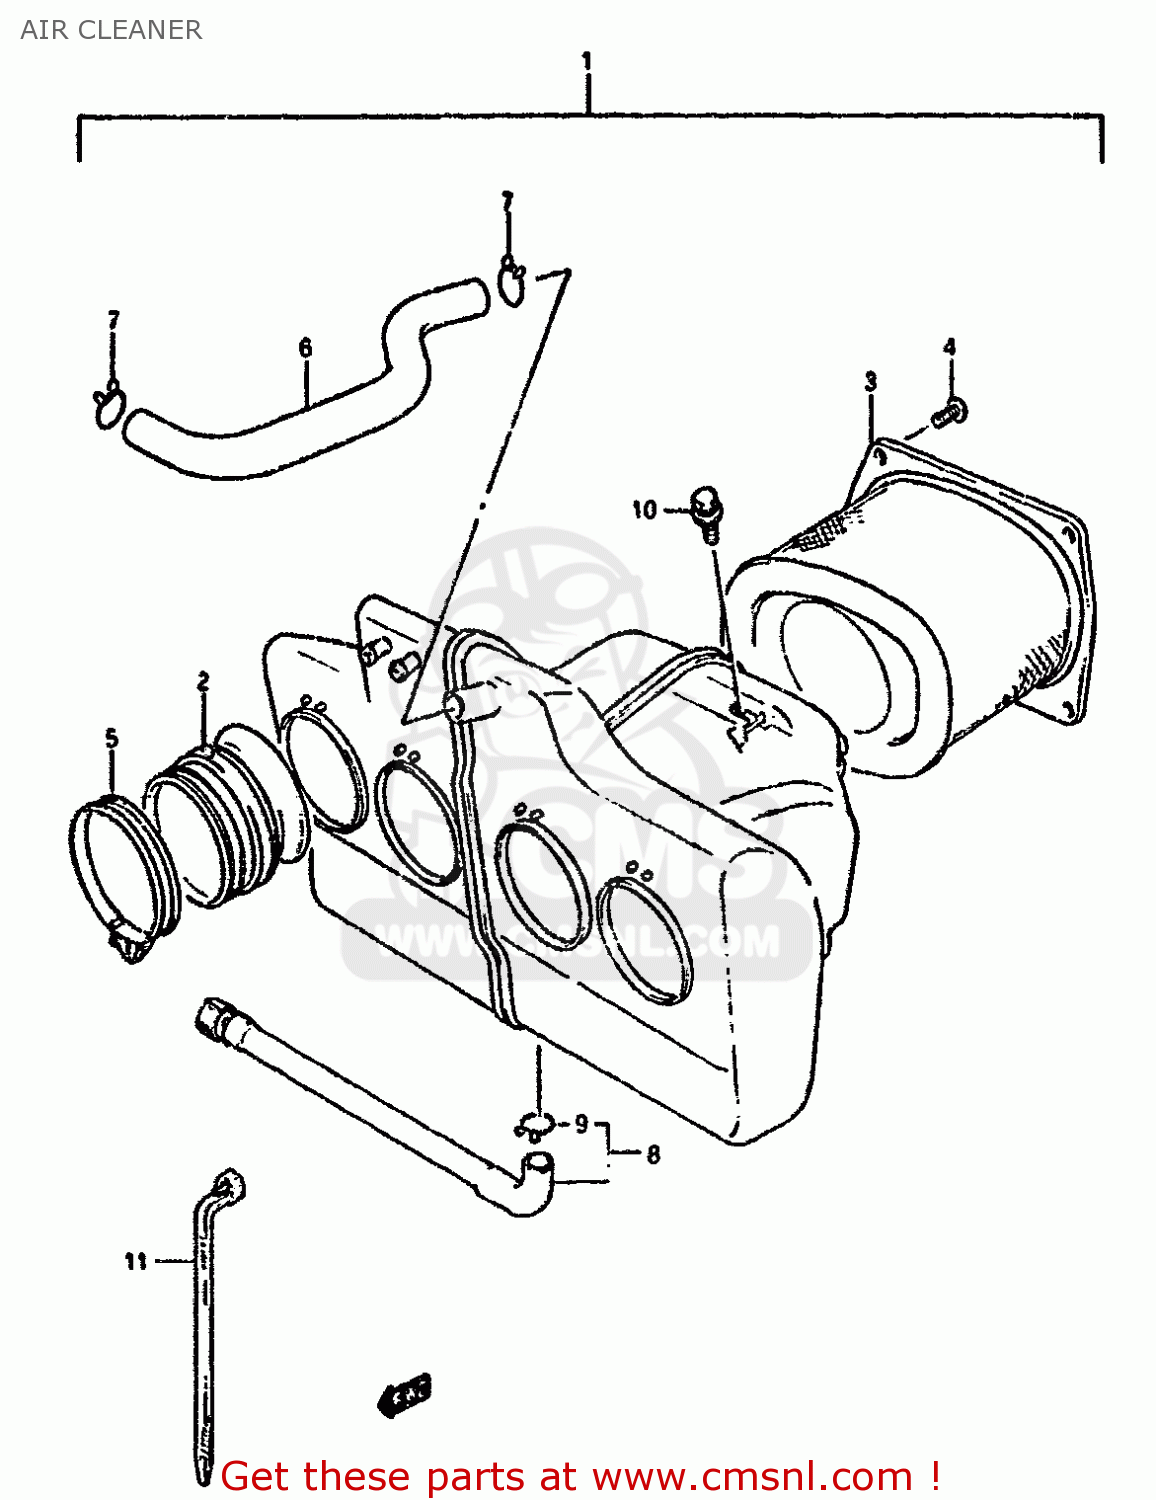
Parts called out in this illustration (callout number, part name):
1	CLEANER ASSY,AIR
2	TUBE,OUTLET
3	FILTER ASSY
4	SCREW, FRONT & REAR
5	CLAMP
6	TUBE,BREATHER
7	CLIP
8	DRAIN TUBE
9	CLIP
10	BOLT
11	CLAMP(L:125)
